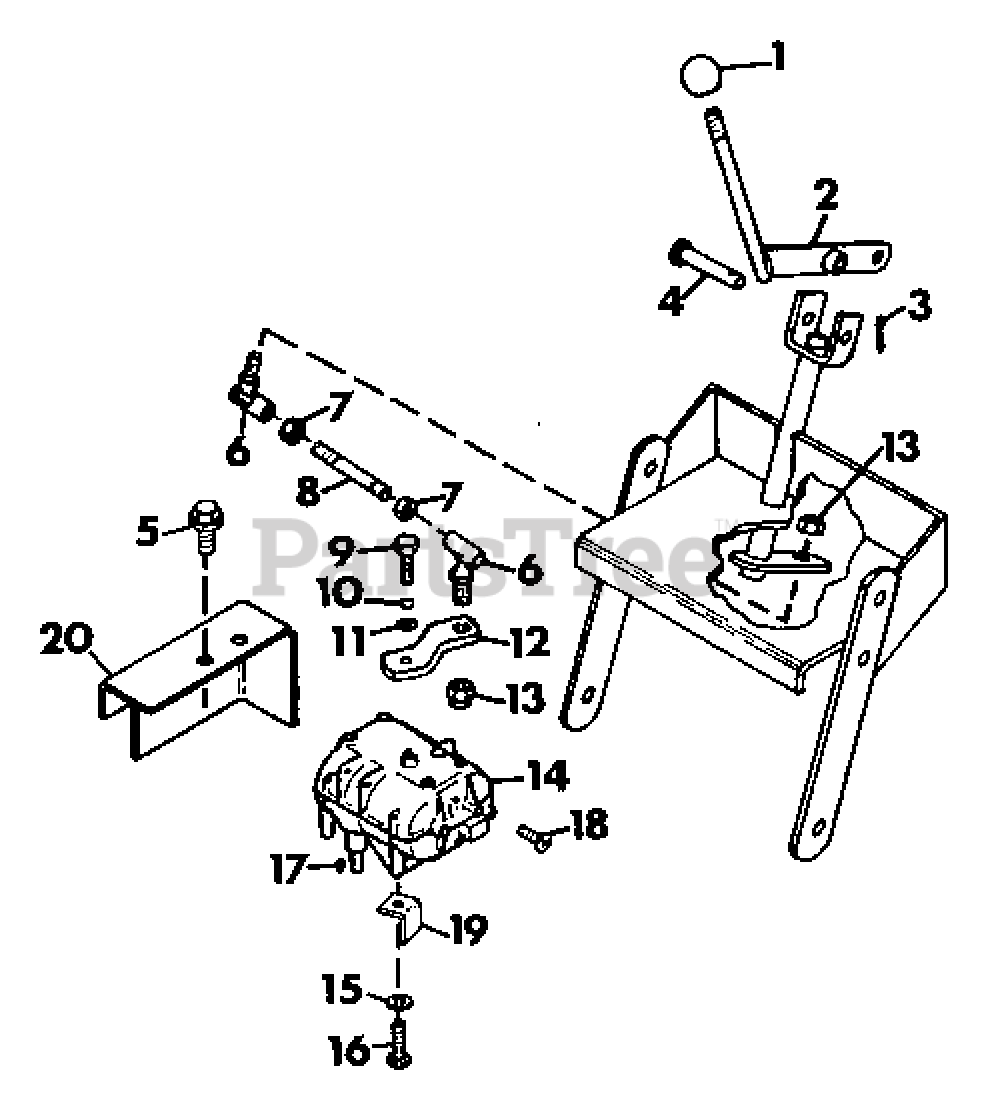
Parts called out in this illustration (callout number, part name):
1	Knob, Control
2	Weldment, Shift Lever
3	Pin, Cotter .09x.75
4	Pin, Clevis
5	Bolt, Self-Tapping 5/16-18x.62
6	Ball Joint, Disconnecting
7	Nut, Hex 1/4-28
8	Rod, Trans. Shifter
9	Bolt, Hex 1/4-28x.50
10	Washer, Lock 1/4
11	Washer, Flat .281x.625x.065
12	Arm, Trans. Shift
13	Nut, Lock 1/4-28
14	Transmission, 5-Speed
15	Washer, Lock 5/16 Reg.
16	Bolt, Hex 5/16-18x.75
17	Key, Woodruff .187x.750 Hard
18	Screw, Tapping 1/4-20x.625 PHD
19	Guide, V-Belt
20	Guard, Transmission Chain
